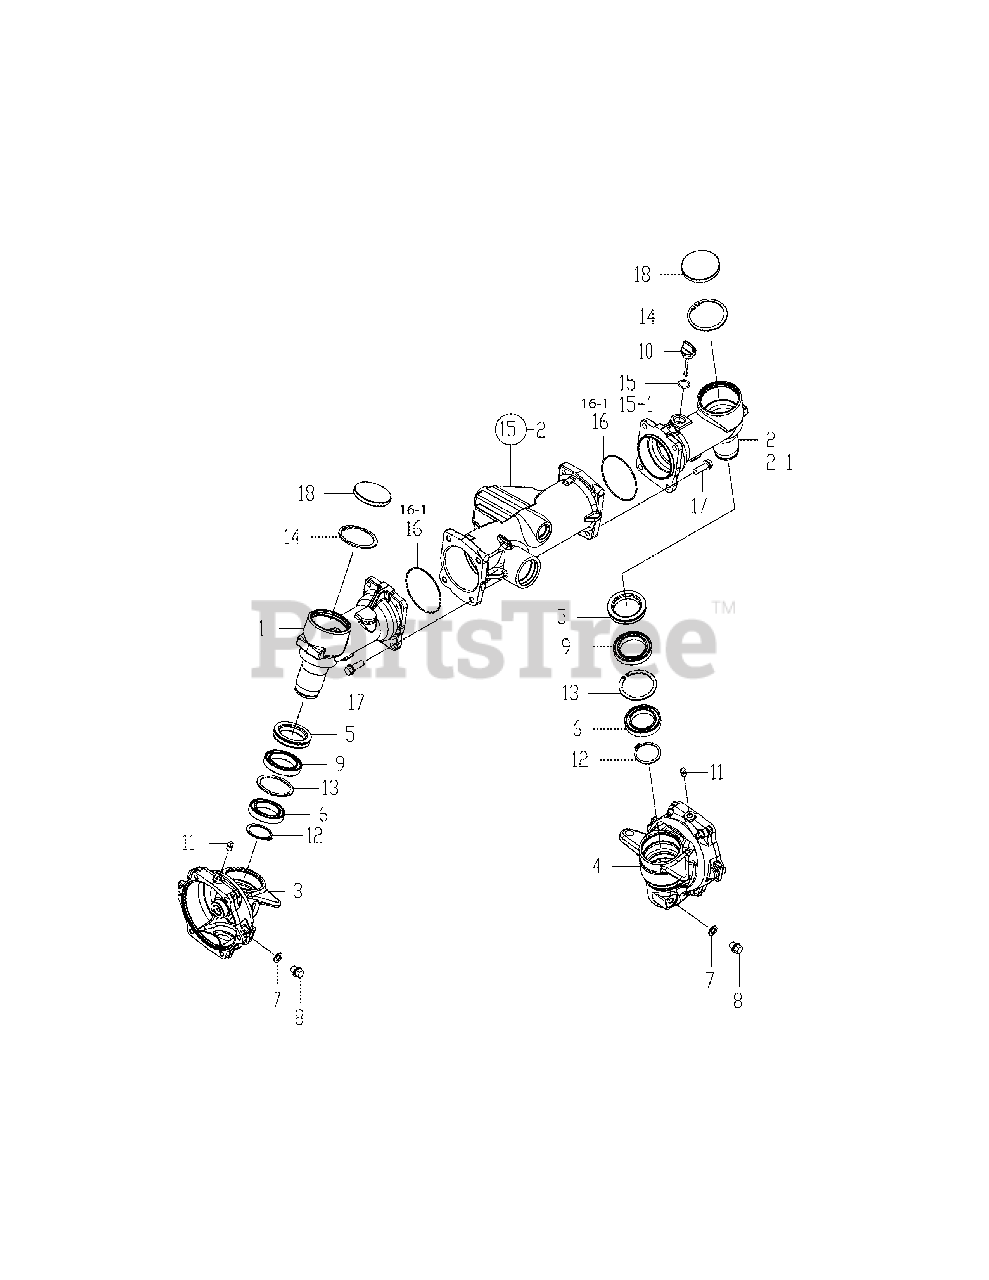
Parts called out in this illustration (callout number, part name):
1	Case L, Front Gear
2	Case R, Front Gear
2-1	Case R, Front Gear
3	Box L, Front Gear
4	Box R, Front Gear
5	Seal Qln 50721013
7	Gasket, 20X12X2
10	Gauge, Oil Level
15-1	Packing, P 18.0
16	Packing, S 90.0
16-1	O-Ring 1A S-85.0
18	Cap, Sealing 72
